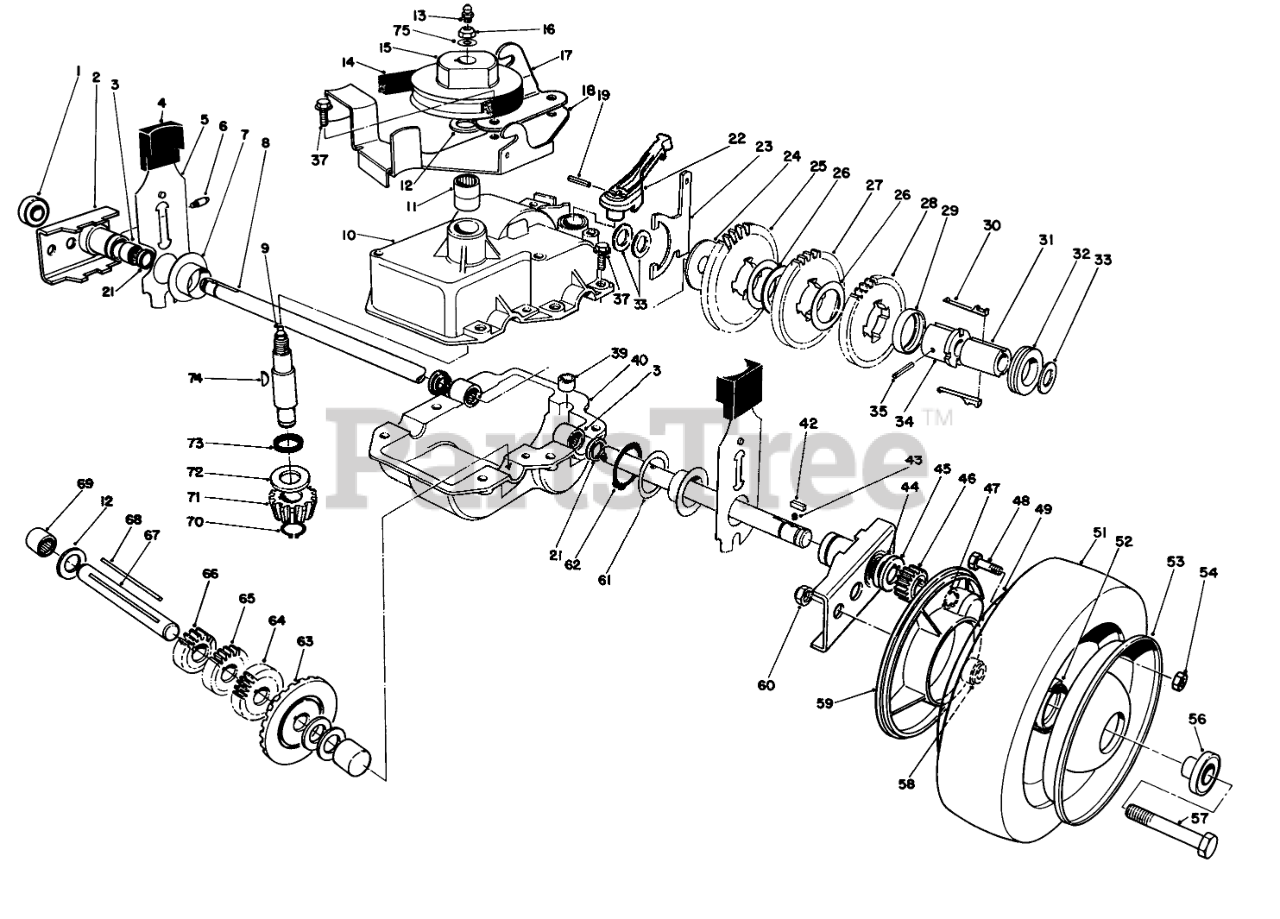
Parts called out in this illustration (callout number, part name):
1	BEARING-WHEEL
2	Pivot Arm Assembly (Incl. Ref. #1, 3, 6 & 21)
3	BEARING-ROLLER
4	KNOB-ARM
5	REAR SPRING ARM ASM
7	CAP-END
8	SHAFT-OUTPUT
9	Shaft-Input (Incl Ref. #13)
10	Upper Case Assembly (Incl. Ref. #11 & 73)
11	BEARING-NEEDLE
12	WASHER-THRUST
13	FITTING-GREASE, ZERK
14	V-BELT
15	PULLEY
16	NUT-HEX
17	Bracket-Traction Engage
18	Belt Guide Bracket
19	PIN-COIL
21	SEAL-OIL
22	LEVER-SHIFT
23	YOKE-SHIFT
24	WASHER
26	WASHER
27	GEAR-42T
28	GEAR-38T
29	RETAINER-KEY
30	KEY-SHIFT
31	SLEEVE
32	COLLAR-SHIFT
33	WASHER-PLAIN
34	SLEEVE-GEAR
35	PIN-GROOVE
37	SCREW-HWHTF
39	BUSHING-YOKE
40	CASE-GEAR, LOWER
42	KEY RECTANGULAR
43	SPRING-COMPRESSION
44	WASHER-THRUST, OUTER
45	WASHER-THRUST, OUTER
46	GEAR-PINION
47	RING-RETAINING
48	SCREW-HH
49	Wheel-Half
52	HUB-BEARING
53	Wheel-Half
54	NUT-LOCK, NI
56	Bearing-Wheel
57	SCREW-HH
58	SPACER-COVER, WHEEL
59	COVER-WHEEL
60	NUT-LOCK, CONE
61	WASHER
62	RING-RETAINING
63	GEAR-BEVEL
64	GEAR-18T
65	GEAR-14T
66	GEAR-12T
67	SHAFT-INTERMEDIATE
69	BEARING-NEEDLE, CLOSED
70	RING-RETAINING
71	PINION-BEVEL
72	WASHER-THRUST
74	KEY-WOODRUFF
75	WASHER-FLAT
